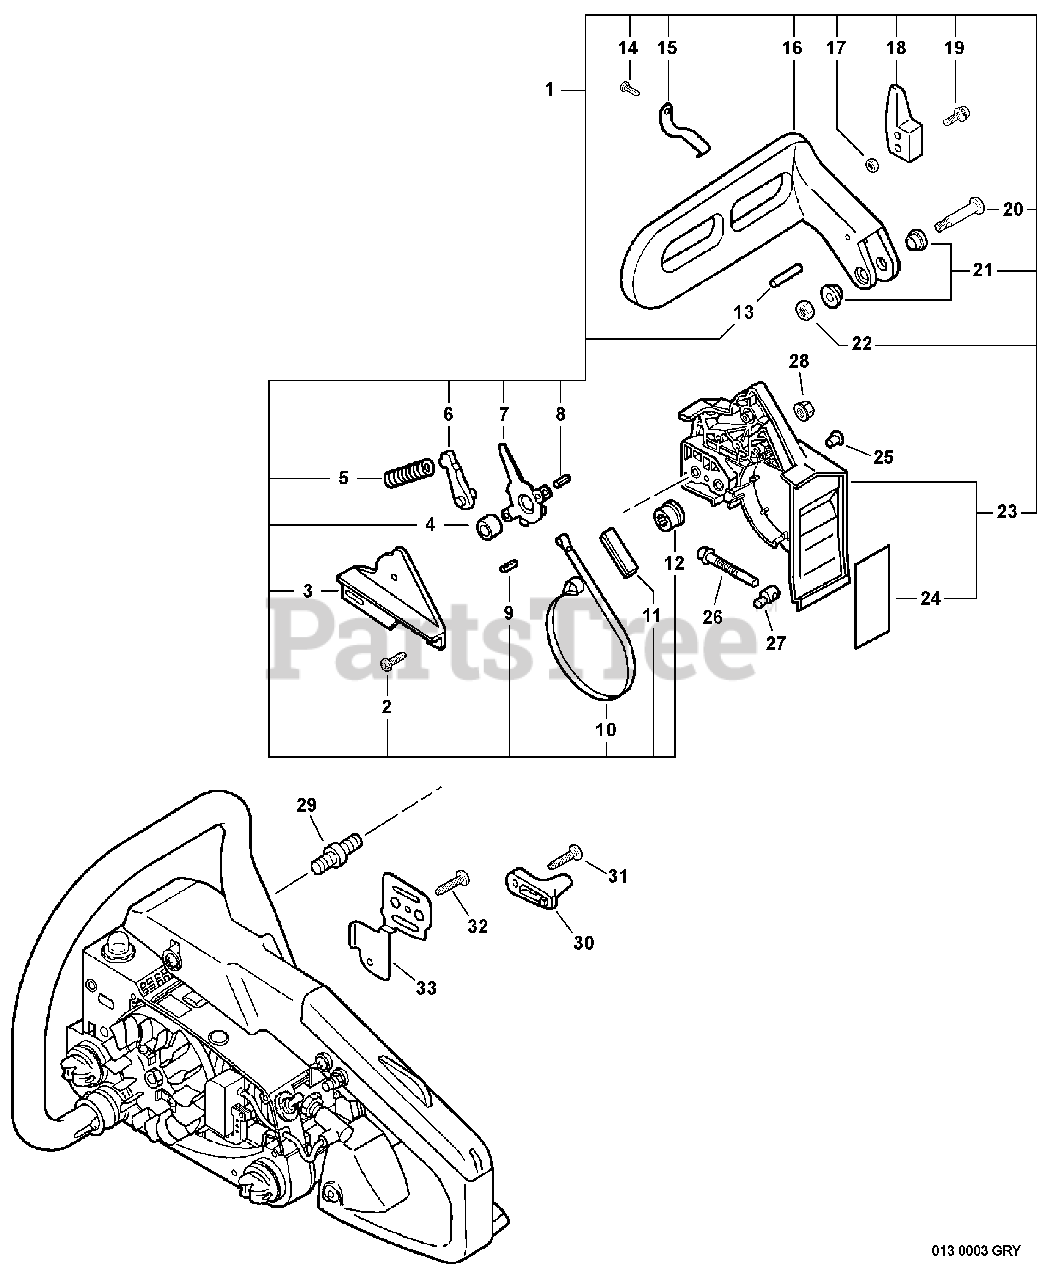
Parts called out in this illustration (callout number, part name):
1	BRAKE ASSY, CHAIN
2	SCREW 4×12
3	COVER, BRAKE
4	SPACER 8×12×9
5	SPRING, COMPRESSION
6	STOPPER, BRAKE
7	LEVER, BRAKE
8	PIN, SPRING 4×8.8
9	PIN, SPRING 2.5×12
10	BAND, BRAKE
11	SEAL, BRAKE
12	ADJUSTER, BRAKE
13	ROLLER 4×23.8
14	SCREW 4×10
15	SPRING, FLAT
16	LEVER, BRAKE
18	WEIGHT, BRAKE
19	SCREW 4×22
20	SCREW 5×32
21	COLLAR 5.3×10×13×L5
22	NUT, LOCK M5
23	GUARD, SPROCKET - GRAY
24	SHIELD, HEAT 35×60×0.10
27	TENSIONER, CHAIN
28	NUT, FLANGE M6
29	BOLT, STUD 6
30	CHAIN CATCHER
31	SCREW, TAPPING 5×20
32	SCREW 4×10
33	PLATE, GUIDE
